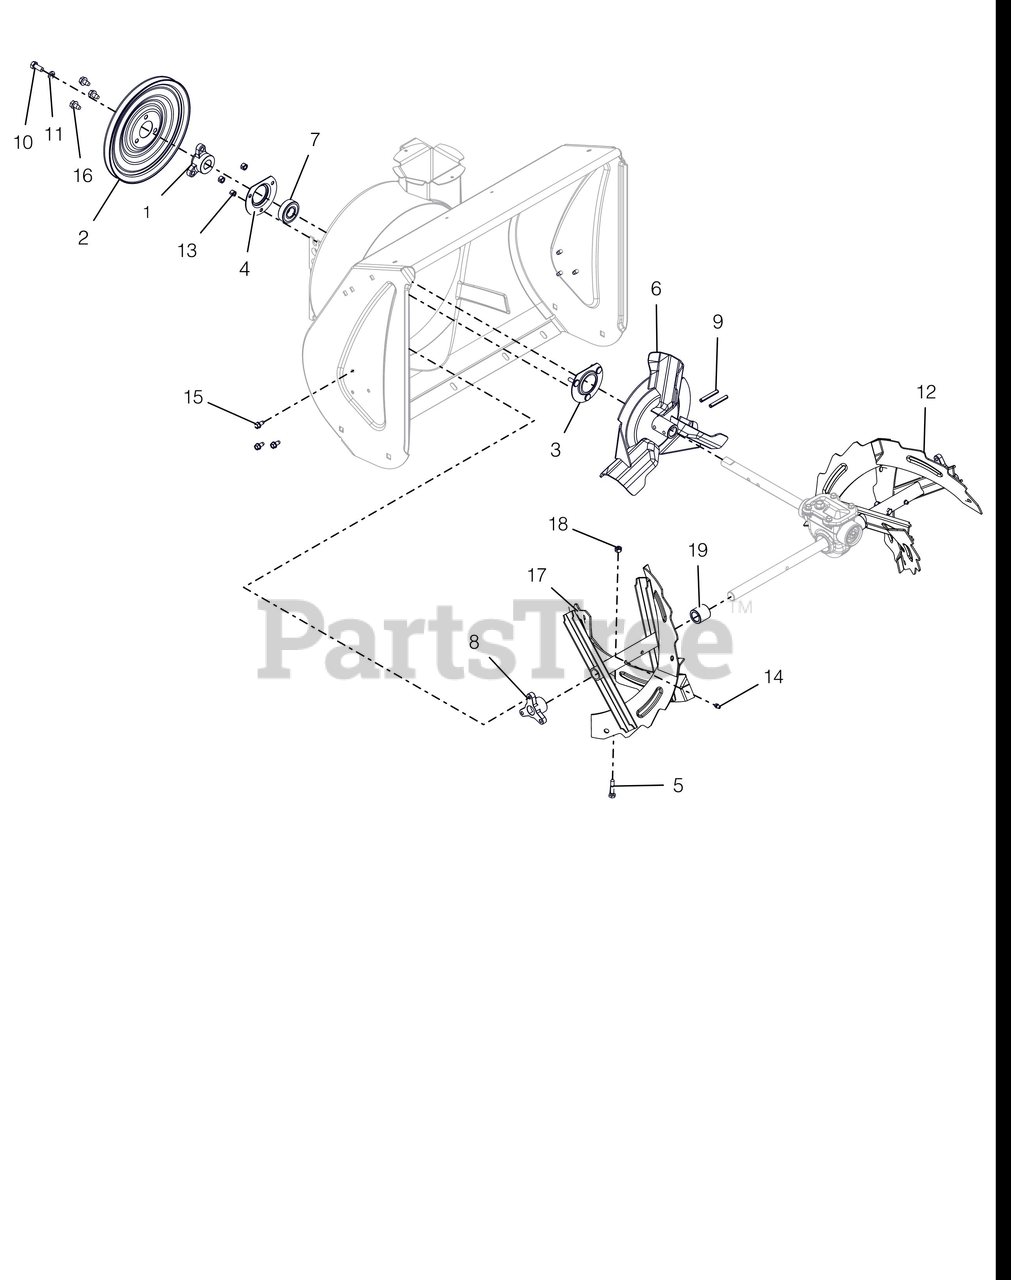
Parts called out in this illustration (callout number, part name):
1	PULLEY HUB, BOLT-ON D-BORE .75
2	PULLEY,SPIN FORM SINGLE GROOVE
3	BEARING FLANGE
4	BEARING FLANGE
5	SHEAR BOLT
6	IMPELLER, COMPACT 12" 3-BLADE
7	BRG-BALL .750X1.750X.50
8	BUSHING, RAKE SHAFT .75"
9	PIN-ROLL .250X1.75
10	BLT-HEX .31-24X.75 YWZC GR5
11	WSHR-LK .312X.097 HVY YWZC
12	AUGER, LH 20", BLK SERR W/ZERK
13	@NUT-LK-CTR .25-20 YWZC
14	ZERK,FITTING .25X.125 DRIVE IN
15	SCR-TAP .25-20X.50 HWH TR YWZ
16	@SCR-TAP .31-18X.50 HWH TR YWZ
17	AUGER, 20" RH, BLK SERR W/ZERK
18	@NUT-LK-CTR .25-20 YWZC
19	BSHG-SLV .75X1.12X1.062 NYL BK
